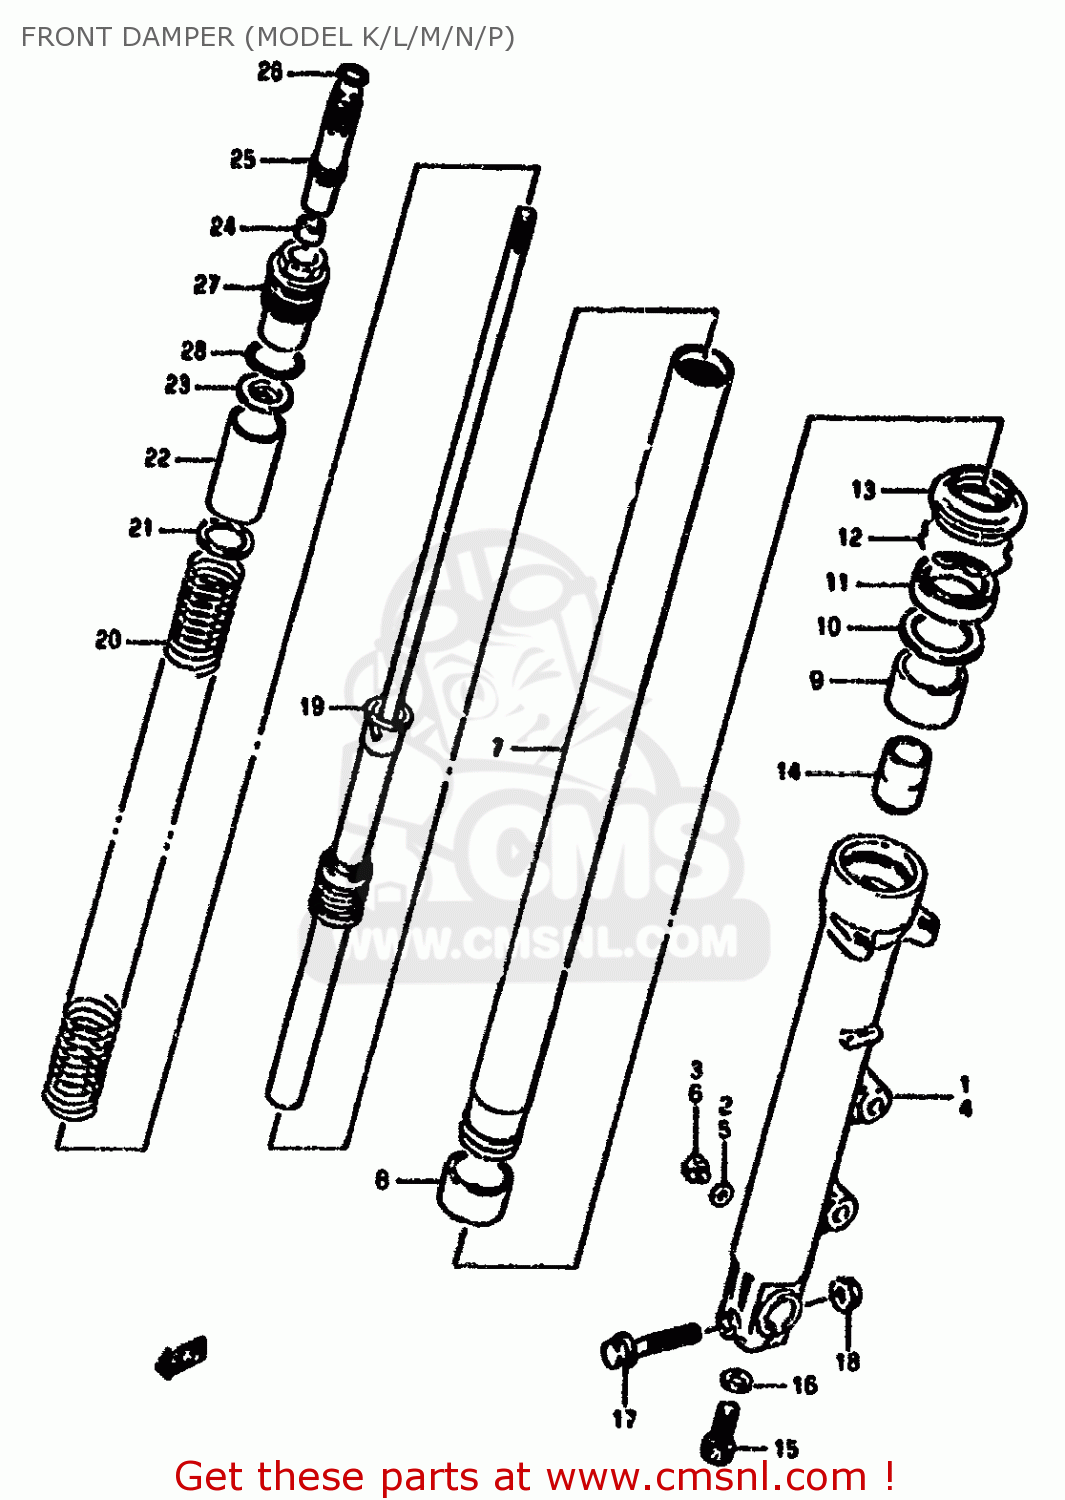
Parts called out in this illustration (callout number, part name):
1	TUBE,OUTER,RIGHT
2	GASKET,DRAIN,PLUG (NAS)
3	BOLT
4	TUBE,OUTER,LEFT
5	GASKET,DRAIN,PLUG (NAS)
6	BOLT
7	TUBE,INNER
8	BUSH,SLIDE
9	BUSH,GUIDE
10	SPACER,SEAL
11	SEAL,OIL
12	CIRCLIP,FORK OIL SEAL
13	BOOT
14	PIECE,OIL LOCK
15	BOLT(8X27)
16	GASKET (NAS)
17	BOLT 8X55
18	NUT
19	DAMPER
20	SPRING,FR FORK
21	JOINT,SPRING
22	COLLAR,SPRING(32.9X34X50)
23	SEAT,SPRING,UPPER
24	NUT,ROD
25	ADJUSTER,SPRING
26	O RING
27	BOLT,FORK
28	O RING
